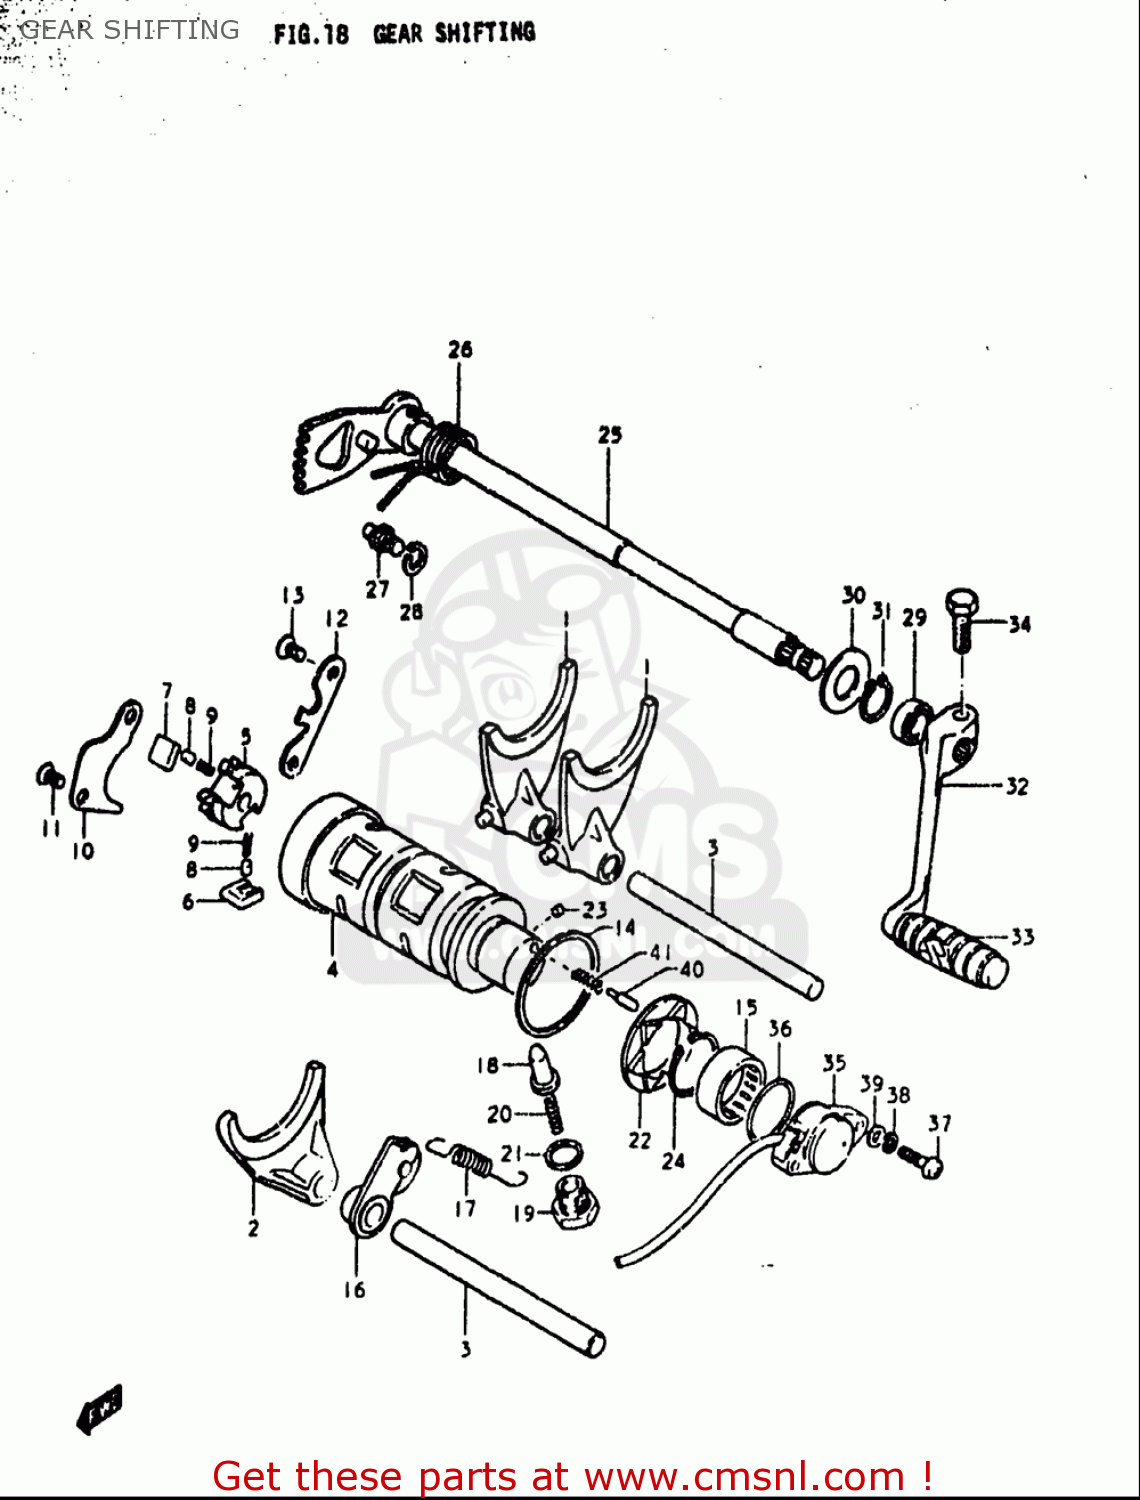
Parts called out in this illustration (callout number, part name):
1	FORK,GEAR SHIFT NO.1
2	FORK,GEAR SHIFT NO.3
3	SHAFT,GEAR SHIFT FORK
5	GEAR,GEAR SHIFT CAM DRIVEN
6	PAWL,GEAR SHIFT NO.1
7	PAWL,GEAR SHIFT NO.2
8	PIN(5X8)
9	SPRING
10	LIFTER,GEAR SHIFT PAWL
11	SCREW
12	GUIDE,GEAR SHIFT CAM
13	SCREW
14	WASHER(40X45X1)
15	BEARING(25X32X12)
16	STOPPER,GEAR SHIFT CAM
17	SPRING
18	STOPPER,GEAR SHIFT CAM NO.2
19	HOLDER,GEAR SHIFT CAM STOP SPR
20	SPRING
21	GASKET(14X19.2X2) (NAS)
22	PLATE,GEAR SHIFT CAM STOPPER
23	PIN
24	CIRCLIP
26	SPRING
27	STOPPER,GEAR SHIFT ARM
28	WASHER,LOCK
29	SEAL,OIL (12X22X9)
30	WASHER (12.5X26X1.6)
31	CIRCLIP,12 MM
32	LEVER ASSY,GEAR SHIFT
33	RUBBER,GEAR SHIFT PEDAL
34	BOLT
35	TERMINAL BASE ASSY,GEAR SHIFT
36	O RING(D:2.4,ID:26.2)
37	SCREW
38	WASHER,LOCK
39	WASHER
40	PIN(5X15.5)
41	SPRING
